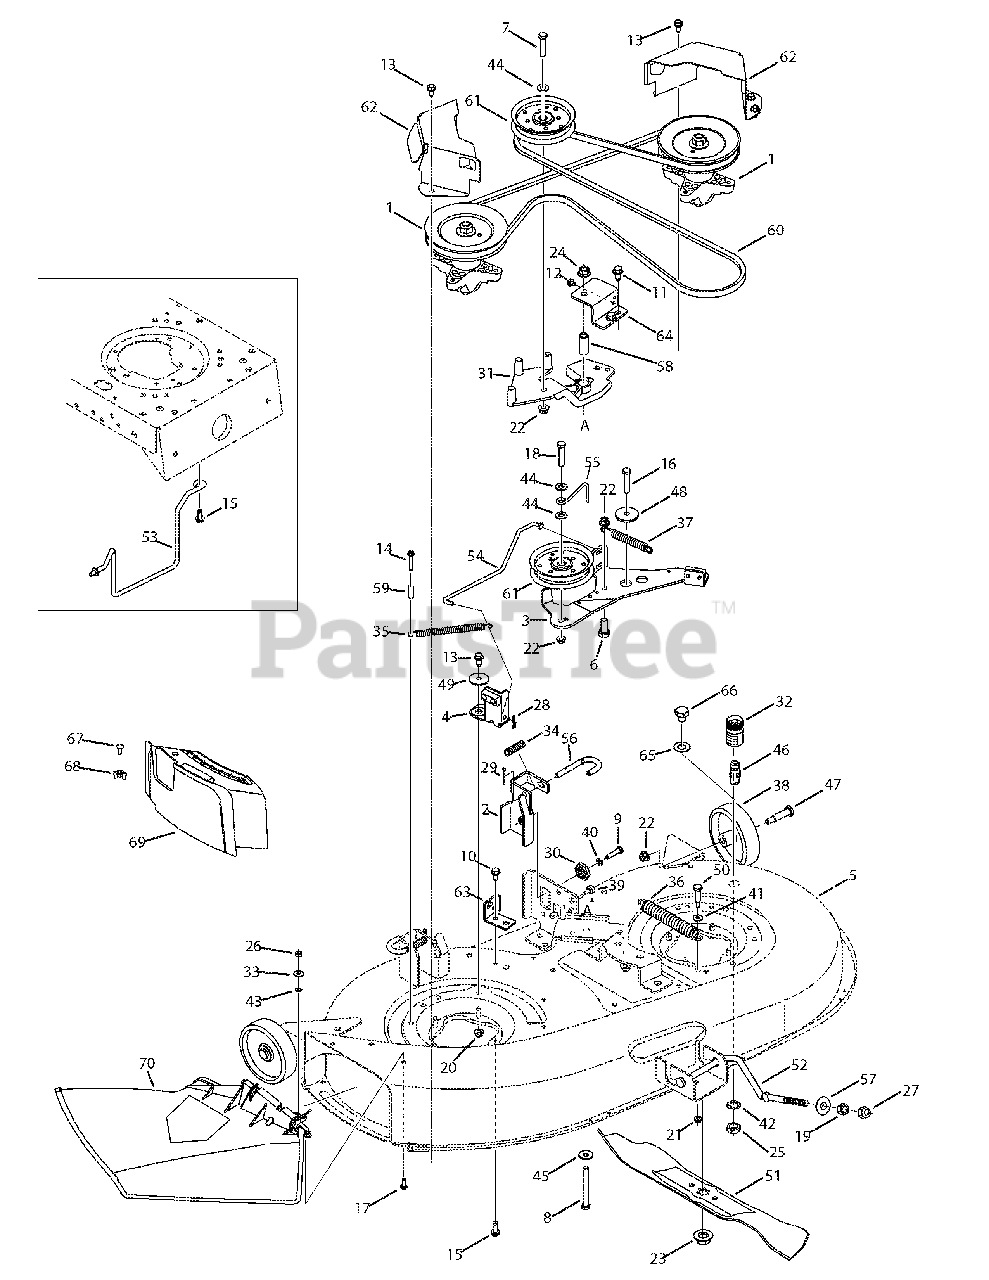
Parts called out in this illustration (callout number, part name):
1	Spindle Assembly Pulley 6.3 Dia
6	Screw, 3/8-16 x .75 GR5 STD
7	Screw, 3/8-16 x 1.75 GR5 STD
8	Screw, 7/16-20 x 3.00 GR5 STD
9	Screw, 5/16-18 x 1.25 GR5 STD
10	Screw, 5/16-18 x 0.75
11	Screw, 3/8-16 x 0.750
12	Screw, 1/4-20 x 0.375
13	Screw, 5/16-18 x 0.750
14	Screw, 1/4-20 x 1.500
15	Screw, 5/16-18 x 0.750
16	Screw, 3/8-16 x 1.25
17	Screw, 1/4-20 x .75
18	Screw, 3/8-16 x 2.00
19	Hex Nut, 1/2-13
20	Flange Lock Nut, 5/16-18
21	Flange Lock Nut, 1/4-20
22	Flange Lock Nut, 3/8-16
23	Flange Nut, 5/8-18
24	Flange Lock Nut, 7/16-20
25	Hex Nut, M16-1.5 DIN 936
26	Hex Nut, 1/4-20
27	Hex Lock Nut, 1/2-13
28	Cotter Pin, .072 Dia. x 1.13 Lg.
29	Cotter Pin, 1/8 x 1.25
30	Deck Gear Adjustment
32	Water Nozzle Adapter
33	Push Nut, .25 ID x .50 OD
34	Compression Spring .531 x 1.75
35	Extension Spring, .500 x 6.375
36	Extension Spring, .94 x 6.74
37	Extension Spring, .53 x 4.75
38	Deck Wheel, 5.0 x 1.38
39	Bumper, .62 Dia. x .3
40	Lock Washer, 5/16
41	Flat Washer, .28 x .74 x .063
42	Lock Washer, 5/8
43	Bell Washer, .265 x.75 x .062
44	Flat Washer, .406 x .875 x .059
45	Flat Washer, .450 x 1.250 x .164
46	Deck Water Nozzle
47	Shoulder Bolt, .496 x 1.525
48	Shoulder Spacer, .8840 x .190
49	Shoulder Spacer, .5000 X .1475
50	Shoulder Screw, .374 x 1.16
51	3 in 1 Star Blade 21.23"LG
52	Adjustible Front Deck Rod,
54	Brake Control Ride, 42"
55	Belt Keeper Rod, 42" IDLER
56	Deck Release Handle Rod
57	Deck Lift Pivot Cup
58	Spacer, .455 X .697 X 1.585
59	Spacer, .260 x .372 x 1.030
60	V-Belt
61	Idler Pulley, 4.25"DIA
66	Bolt Plug, M16 x 1.5
67	Carriage Screw, 1/4-20 x .62
68	Wing Nut, 1/4-20
69	Mulch Plug
70	Discharge Chute Assembly
